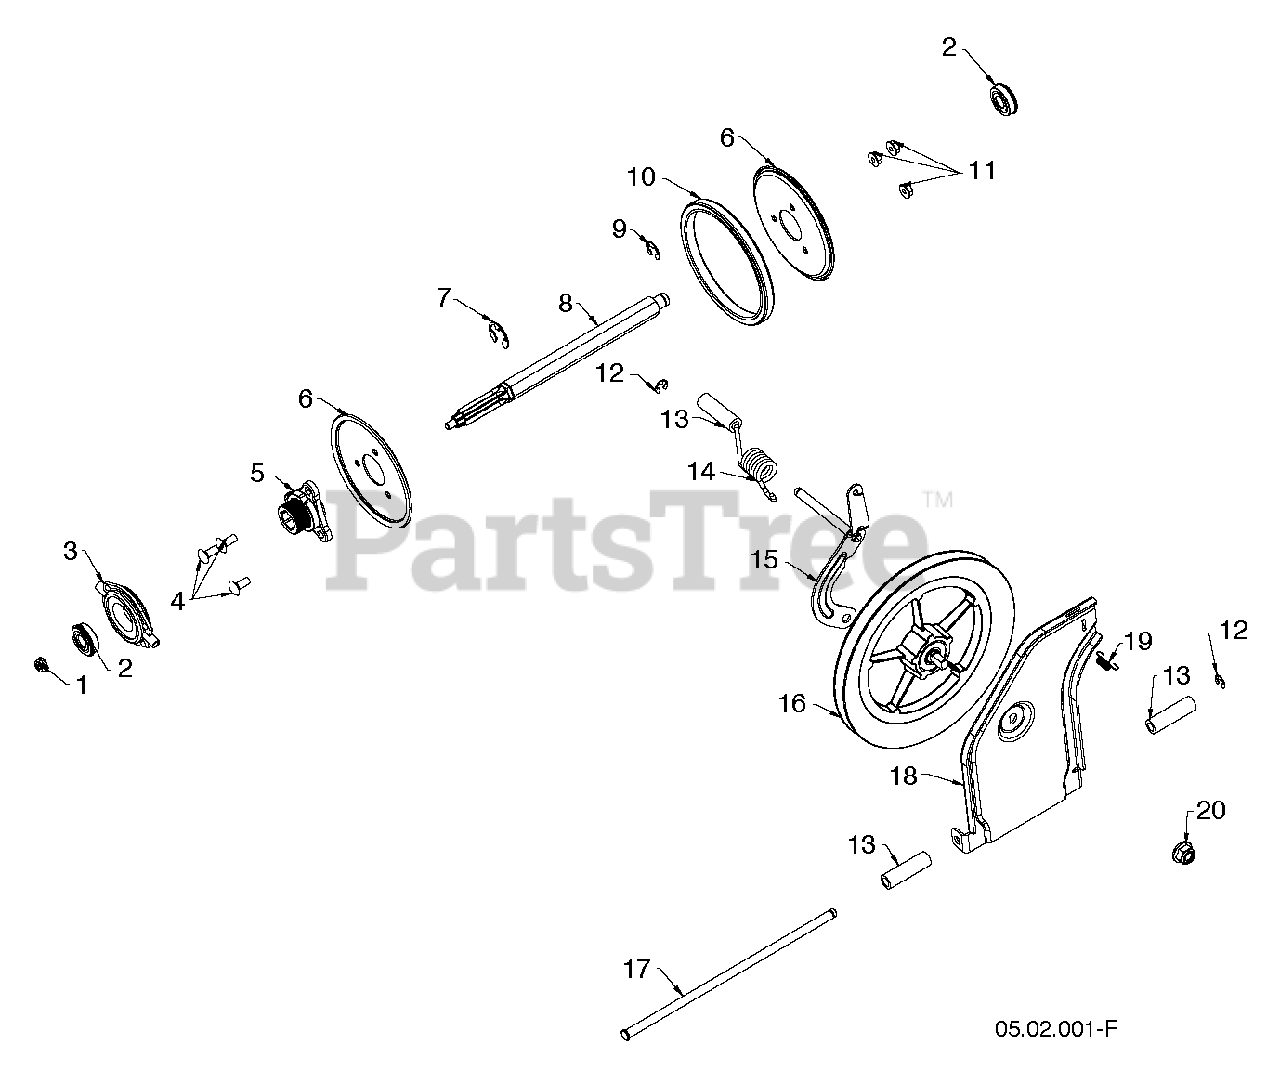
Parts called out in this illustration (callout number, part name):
1	NUT.HEX.FLANGE.LOCK.5/16-18
2	BEARING 9/16 ID. SNR
3	TRUNNION BEARING ASSY
4	BOLT.CARR.SQNK.5/16-18UNC.X3/4
5	HUB.RUBBER.WHEEL
6	PLATE.RUBBER.WHEEL.BLACK
8	SHAFT SHAFT,7T REDUCTION
9	RING.RETAINING.1622-2RSNR.CLER
10	RING RUBBER
11	NUT.LOCK.5/16-18
12	E-RING LT
13	SPACER YOKE, TORSION SPRING
14	SPRING TORSION DRIVE
15	BRACKET.YOKE.ASSEMBLY.479
16	PULLEY.FRICTION.DISC.COMBO
17	ROD.TIP.PLATE
18	PLATE.SWING.FRICTION PULLEY.47
19	SPRING LATCH
20	NUT, 1/2-13 HEX FLG NYLOC ZD
